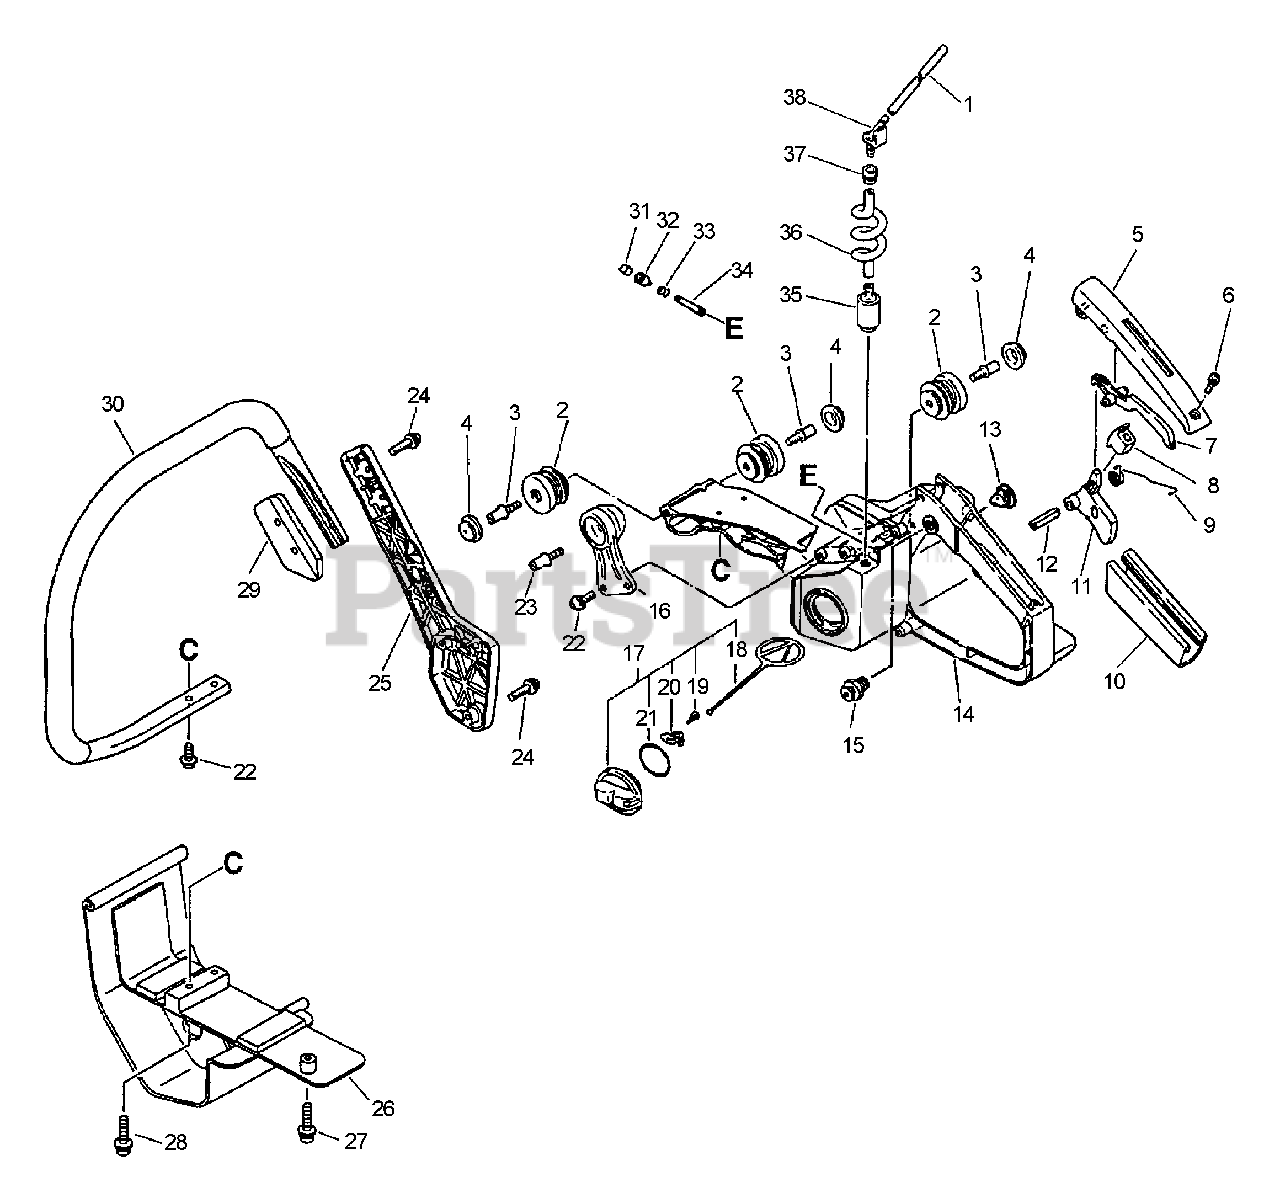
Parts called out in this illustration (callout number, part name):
1	PIPE, FUEL - 3×6×100
4	CAP, CUSHION
5	COVER, HANDLE
6	SCREW 4×14
7	LEVER, THROTTLE LOCKOUT
8	CUSHION, THROTTLE
9	SPRING, THROTTLE RETURN
11	TRIGGER, THROTTLE - ORANGE
12	PIN, SPRING Ø5×25 MM
14	HANDLE - REAR
15	LOCK, THROTTLE TRIGGER
17	CAP ASSY, FUEL
18	CONNECTOR, CAP L= 60 MM
19	SCREW, TAPPING 3×8
20	RETAINER, CONNECTOR
21	O-RING 29
22	BOLT 5×14
24	SCREW 5×20
25	BRACKET, HANDLE
25	BRACKET, GRAY HANDLE
27	BOLT 5×25
28	BOLT 5×30
29	BRACKET, HANDLE
30	HANDLE, FRONT
31	VENT ASSY
32	HOLDER, VENT
34	PIPE, VENT
35	FILTER, FUEL
36	PIPE, FUEL
37	GROMMET
38	CONNECTOR, PIPE
